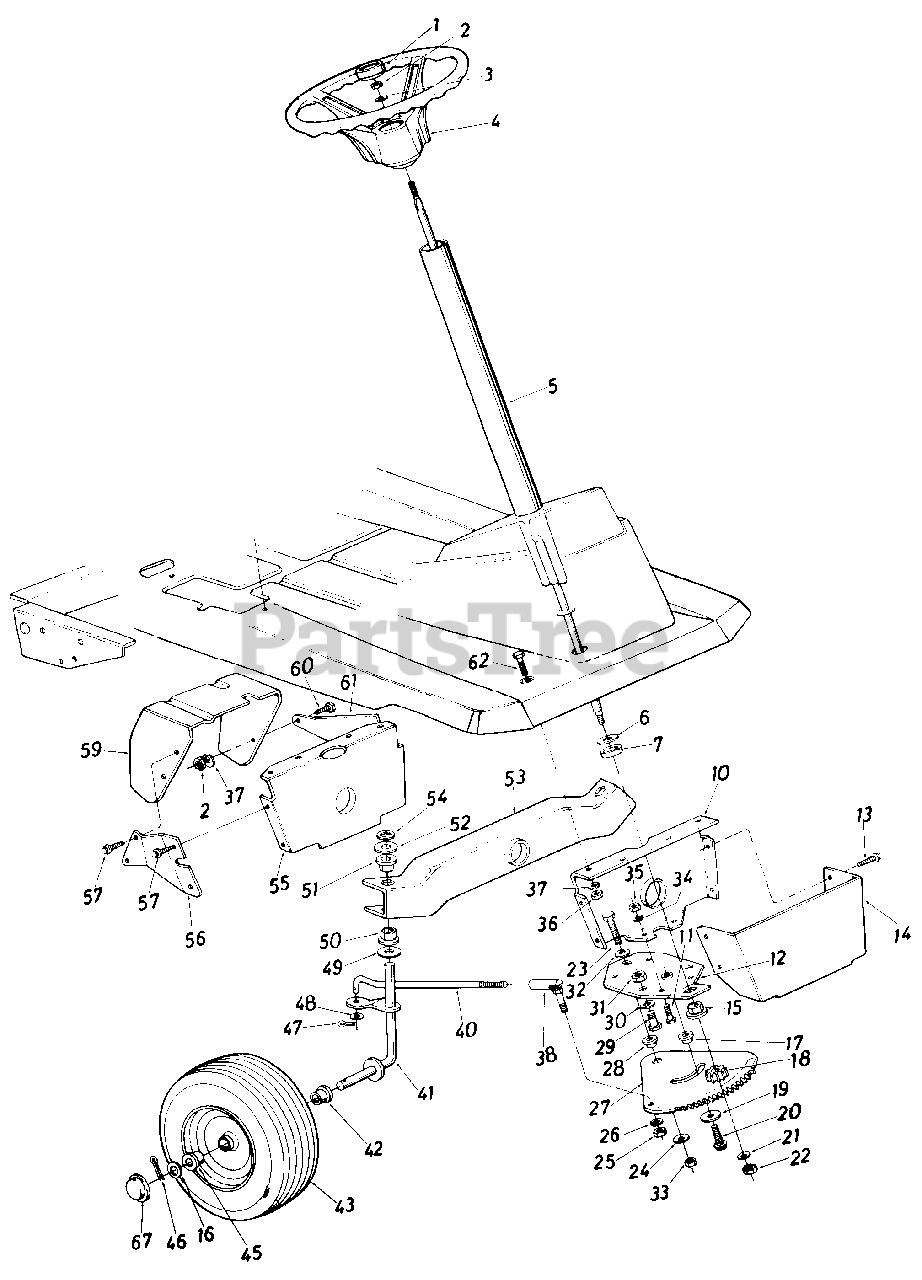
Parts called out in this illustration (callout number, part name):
1	Steering Wheel Cap
2	Hex Nut 5/16-18 Thd.
3	Bell-Wash. .345" I.D. x .88" O.D.
4	Steering Wheel Ass'y.
5	Steering Shaft Ass'y.
6	Fl-Wash. .62" I.D. x 1.50" O.D.
7	Spacer (Plastic)
10	Pivot Bar Bracket
11	Hex Bolt 5/16-18 x .75" Lg.
12	Steering Gear Support Brk't.
13	Hex Wash. Hd. AB-Tap Scr. 1/4 x .62" Lg.
17	Shou Ider Spacer .622 Dia. x .218
18	Steering Pinion Gear
19	Fl-Wash. .385" I.D. x 1.38" O.D.
20	Hex Wash. Hd. Self-Tap Scr. 3/8-16 x 1.25" Lg.
21	Bell-Wash. .345" I.D. x .88" O.D.
22	Hex Nut 5/16-24 Thd.
23	Hex Bolt 3/8-24 x 1.25" Lg. Grade 5
24	Fl-Wash. .385" I.D. x 1.38" O.D.
25	Hex Nut 3/8-24 Thd.
26	L-Wash. 3/8 I.D.
27	Steering Gear Segment
28	Shoulder Spacer .622" Dia. x .218
29	Hex Bolt (Nylon) 1/2-13 x .75" Lg.
30	Fl-Wash. .530" I.D. x .930" O.D.
31	Hex Nut 1/2-13 Thd.
32	Bell-Wash. .385" I.D. x .88" O.D.
33	Hex Nut 3/8-24 Thd.
34	L-Wash. 5/16" I.D.
35	Hex Nut 5/16-18 Thd.
38	Ball Joint Ass'y. 3/8-24 Thd.
40	Steering Tie Rod
41	Front Axle Ass'y. R.H.
42	Flange Bearing .632" I.D.
43	Front Wheel Ass'y. Comp.
46	Cotter Pin 118" Dia. x 1.25" Lg.
47	Cotter Pin 118" Dia. x 1.001' Lg.
48	Fl-Wash. .385" I.D. x .87" O.D.
49	Fl-Wash. .635" I.D. x 1.12" O.D.
50	Hex Flange Bearing
52	Fl-Wash. .635" I.D. x 1.12" O.D.
53	Pivot Bar Ass'y.
54	Speed Nut 5/8" I.D.
55	Pivot Bar Bracket
56	Bracket Reinforcement R.H.
57	Hex Wash. Hd. AB-Tap Scr. 1/4 x .62" Lg.
59	Clutch-Brake Pedal Ass'y.
60	Hex Bolt 5/16-18 x .75" Lg.
61	Bracket Reinforcement L.H .
62	Hex Bolt 5/16-18 x .75" Lg.
